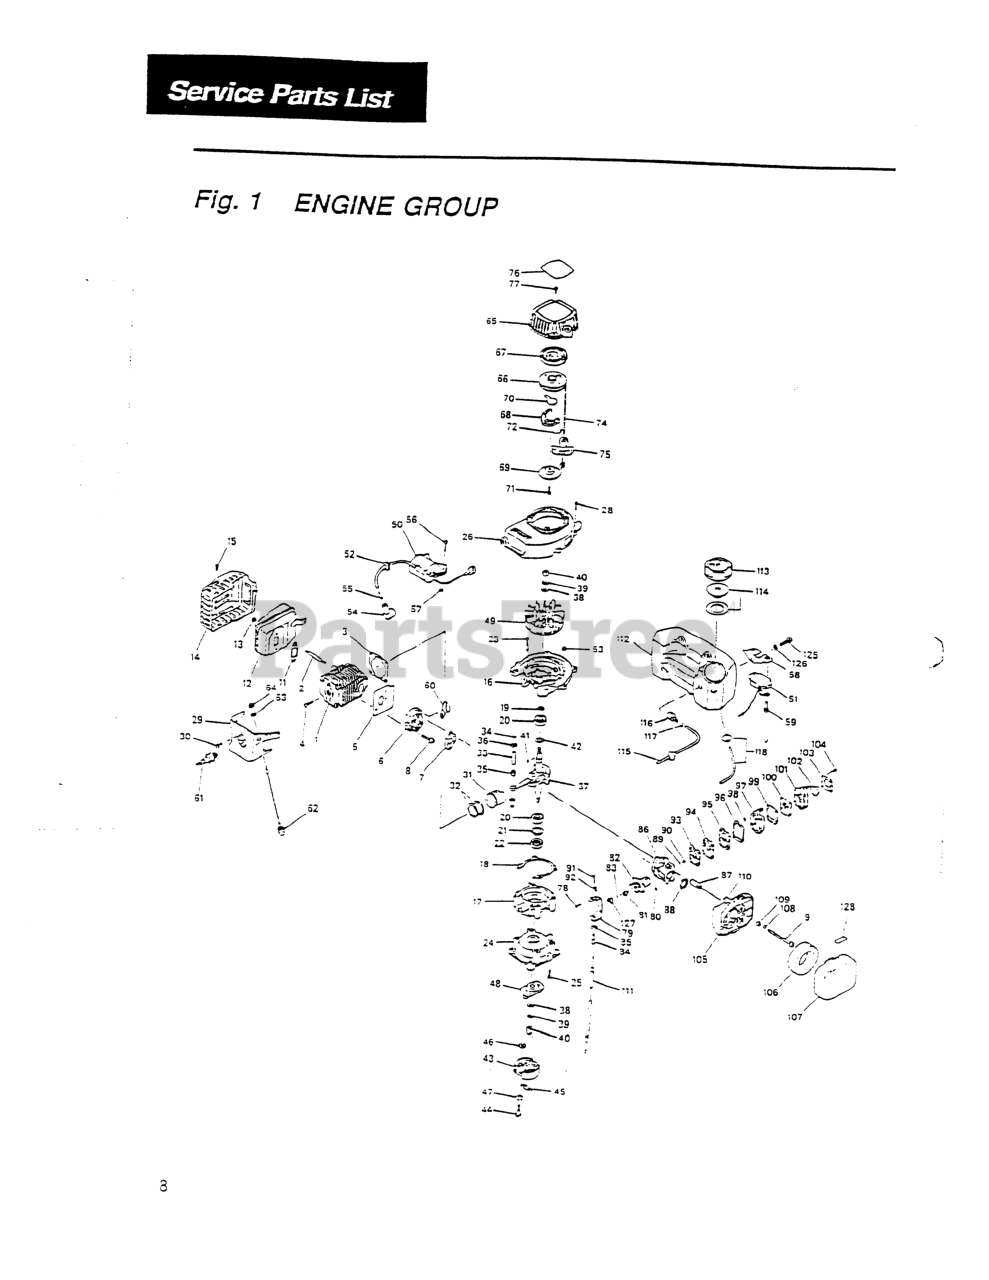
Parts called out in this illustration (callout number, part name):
1	CYLINDER-C
2	STUD
4	SCREW, M5 X 16
6	INSULATOR
13	NUT
16	CRANKCASE (RPLS -21100)
17	CRANKCASE (RPLS -21100)
19	SEAL, OIL
20	BEARING
21	RING, SNAP, M28 x 1.2
22	SEAL, OIL (RPLS 1140-21220)
23	SCREW, M5 x 30(RPLS 0263-00530
24	CASE, CLUTCH (USE 1140-21162)
26	COVER (REPLACES -31101)
28	SCREW, M4 x 14
29	COVER, CYLINDER
31	PISTON (USE 5600-41111)
32	RING, PISTON (RPLS 1850-41210)
33	PIN, PISTON 5x8x26
34	RING, SNAP (RPLS 1101-41320)
36	WASHER
38	WASHER, M8 x 20
39	WASHER, M8 x 1.2
41	KEY
44	BOLT
46	WASHER, FLAT (USE 182303)
51	UNIT
55	SPRING
56	SCREW, M4 x 20
57	WASHER, M5 X .8
59	SCREW, M5 X 12
60	CLAMP
61	SPARK PLUG
63	WASHER
64	NUT
65	STARTER ASSEMBLY
68	RATCHET
69	PLATE (NLA) (RPLS -75240)
70	SPRING, FRICTION
71	SCREW (USE -75261)
72	SPRING
75	KNOB
77	SCREW, M4 X 12
78	SCREW
79	BRACKET, IDLE
80	RING
81	SWIVEL (USE -06040)
82	VALVE, THROTTLE
83	PLUG NEEDLE
85	NUT, CABLE ADJUSTER
86	BODY
87	SLEEVE, MOUNT
88	RING, PACKING (NLA)
89	RING, O
91	SCREW, IDLE AD
92	SPRING, IDLE A
93	GASKET, PUMP
94	DIAPHRAGM
95	PLATE, PUMP (NLA)
96	GASKET, PLATE
97	KIT ONLY
98	SCREEN
99	KIT ONLY
100	DIAPHRAGM (USE 4810-81260)
101	BODY
102	PUMP, PRIMING
103	COVER
104	SCREW
105	BODY
107	COVER
109	SLEEVE (USE 1918-82170)
111	CABLE
114	VALVE COMPLETE
115	PIPE COMP
116	5500-85400 (RRLS. 1750-85300)
125	SCREW, M5 X 16
126	WASHER, M5x.8(RPLS 01624-20508
127	CAP, CABLE END
128	LABEL
NI	CRANKCASE (RPLS -21100)
NI	CARBURETOR-A (NLA)
NI	CLEANER ASSEMBLY
NI	WASHER
